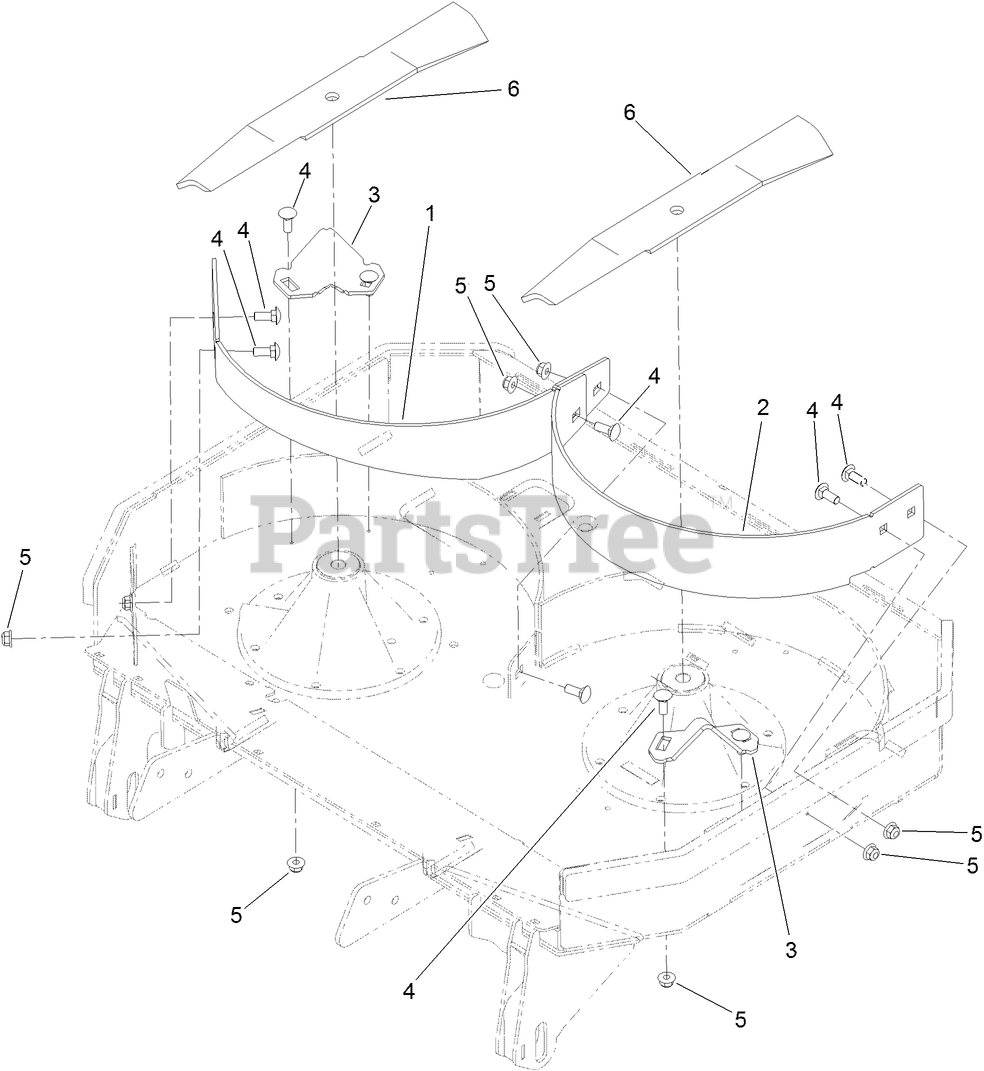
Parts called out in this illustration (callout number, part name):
1	BAFFLE-RH
2	BAFFLE-LH
4	SCREW-HH
5	NUT-HF, NI
6	BLADE-RECYCLER
